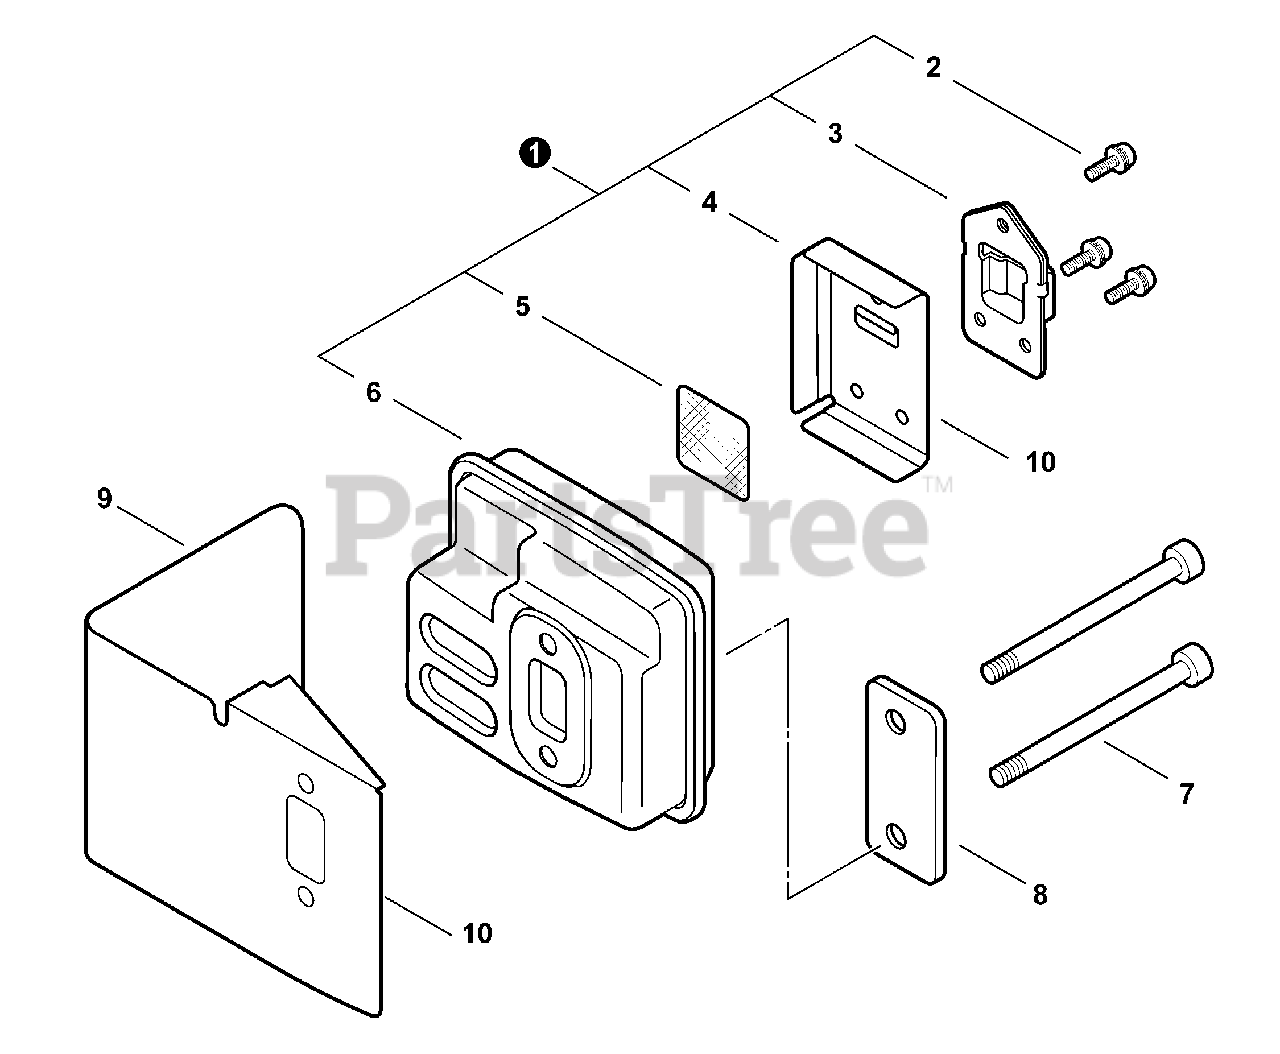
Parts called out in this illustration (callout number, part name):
1	MUFFLER ASSY
2	BOLT, TORX 4×8
3	DEFLECTOR, EXHAUST
4	GASKET, EXHAUST
5	SCREEN, SPARK ARRESTER
6	MUFFLER
7	BOLT, TORX 5×55
8	PLATE, EYE
9	HEAT SHIELD, EXHAUST
10	GASKET KIT
